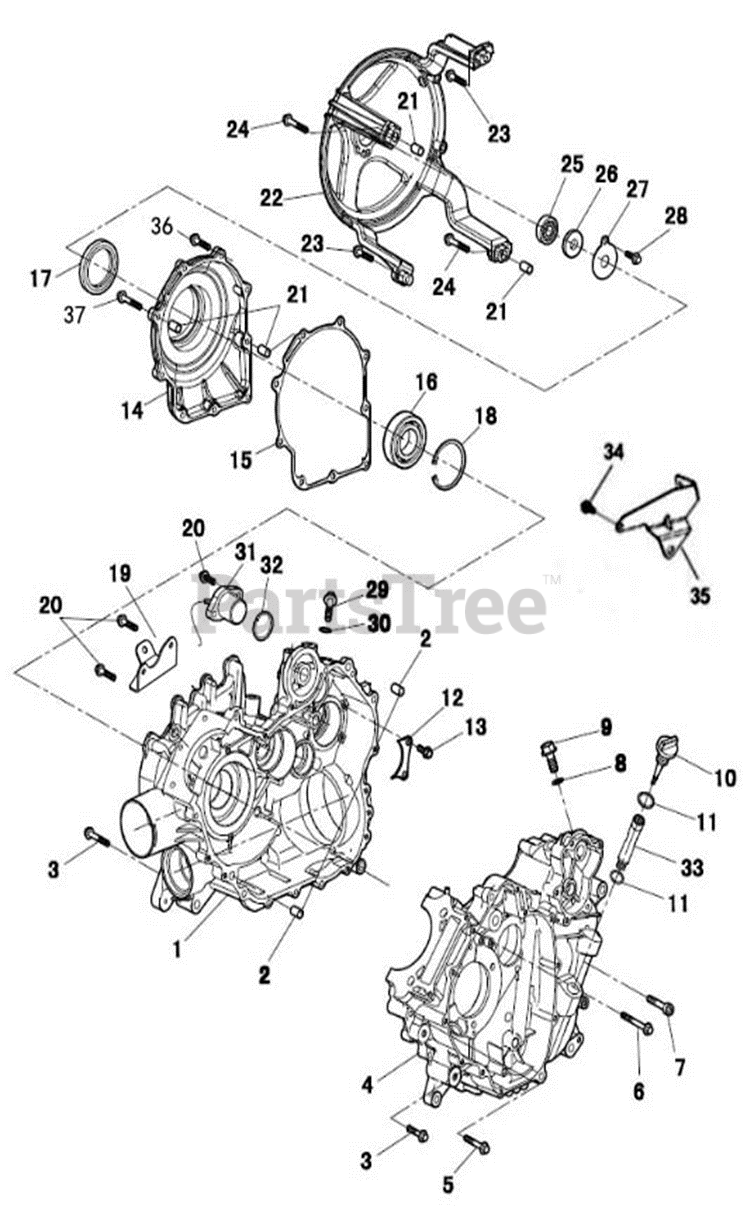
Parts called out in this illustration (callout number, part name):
1	CRANKCASE (RH) (550)
2	DOWEL PIN 9X12X16
3	HEX FLANGE BOLTS M6X30
4	CRANKCASE (LH) (550)
5	HEX FLANGE BOLTS M6X40
6	HEX FLANGE BOLTS M6X85
7	HEX HEAD CAP SCREW M8X40
8	ALUMINUM WASHER 14X20X1.5
9	HEX FLANGE SCREW PLUG M14X1.5X16
10	OIL LEVEL PLUG
11	O-RING 18X3.5
12	MAIN SHAFT BEARING PRESS PLATE
13	HEX FLANGE BOLTS M6X16
14	CLUTCH COVER
15	CLUTCH COVER GASKET
16	BEARING 16010
17	OIL SEAL 35X65X9
19	AIR DUCT BRACKET
20	HEX HEAD BOLT & PLAIN WASHER
21	DOWEL PIN 10X16
22	CLUTCH SHIELD BRACKET
23	HEX FLANGE BOLTS M6X32
24	HEX FLANGE BOLTS M6X40
25	BEARING 62012Z
26	OIL SEAL 12X32X6
27	BRACKET OIL SEAL PRESS PLATE
28	HEX FLANGE BOLTS M6X16
29	HEX FLANGE BOLTS M10X1.25X16
30	ALUMINUM WASHER 10X16X1.2
31	GEAR INDICATOR SENSOR
32	O-RING 29.6X2.4
33	OIL LEVEL GUIDING TUBE
34	HEX FLANGE BOLTS M6X30
35	AIR CLEANER STRAP
36	HEX FLANGE BOLT M6x35
37	HEX FLANGE BOLT M6X45
